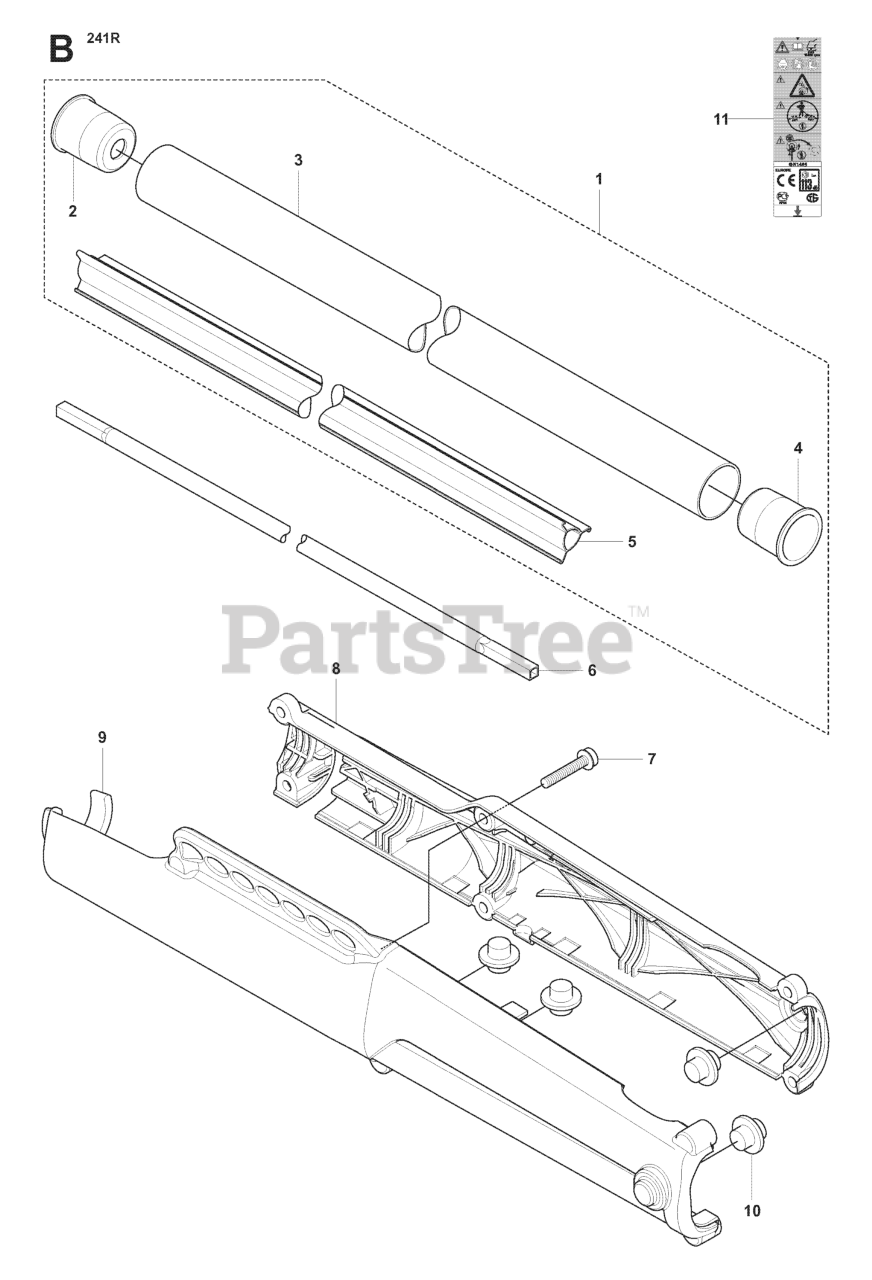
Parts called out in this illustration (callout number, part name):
1	TUBE
2	PLUG
3	TUBE
7	SCREW IHSCFT
10	VIBRATION ABSORBER
11	LABEL WARNING TRIMMERS AND BRU
